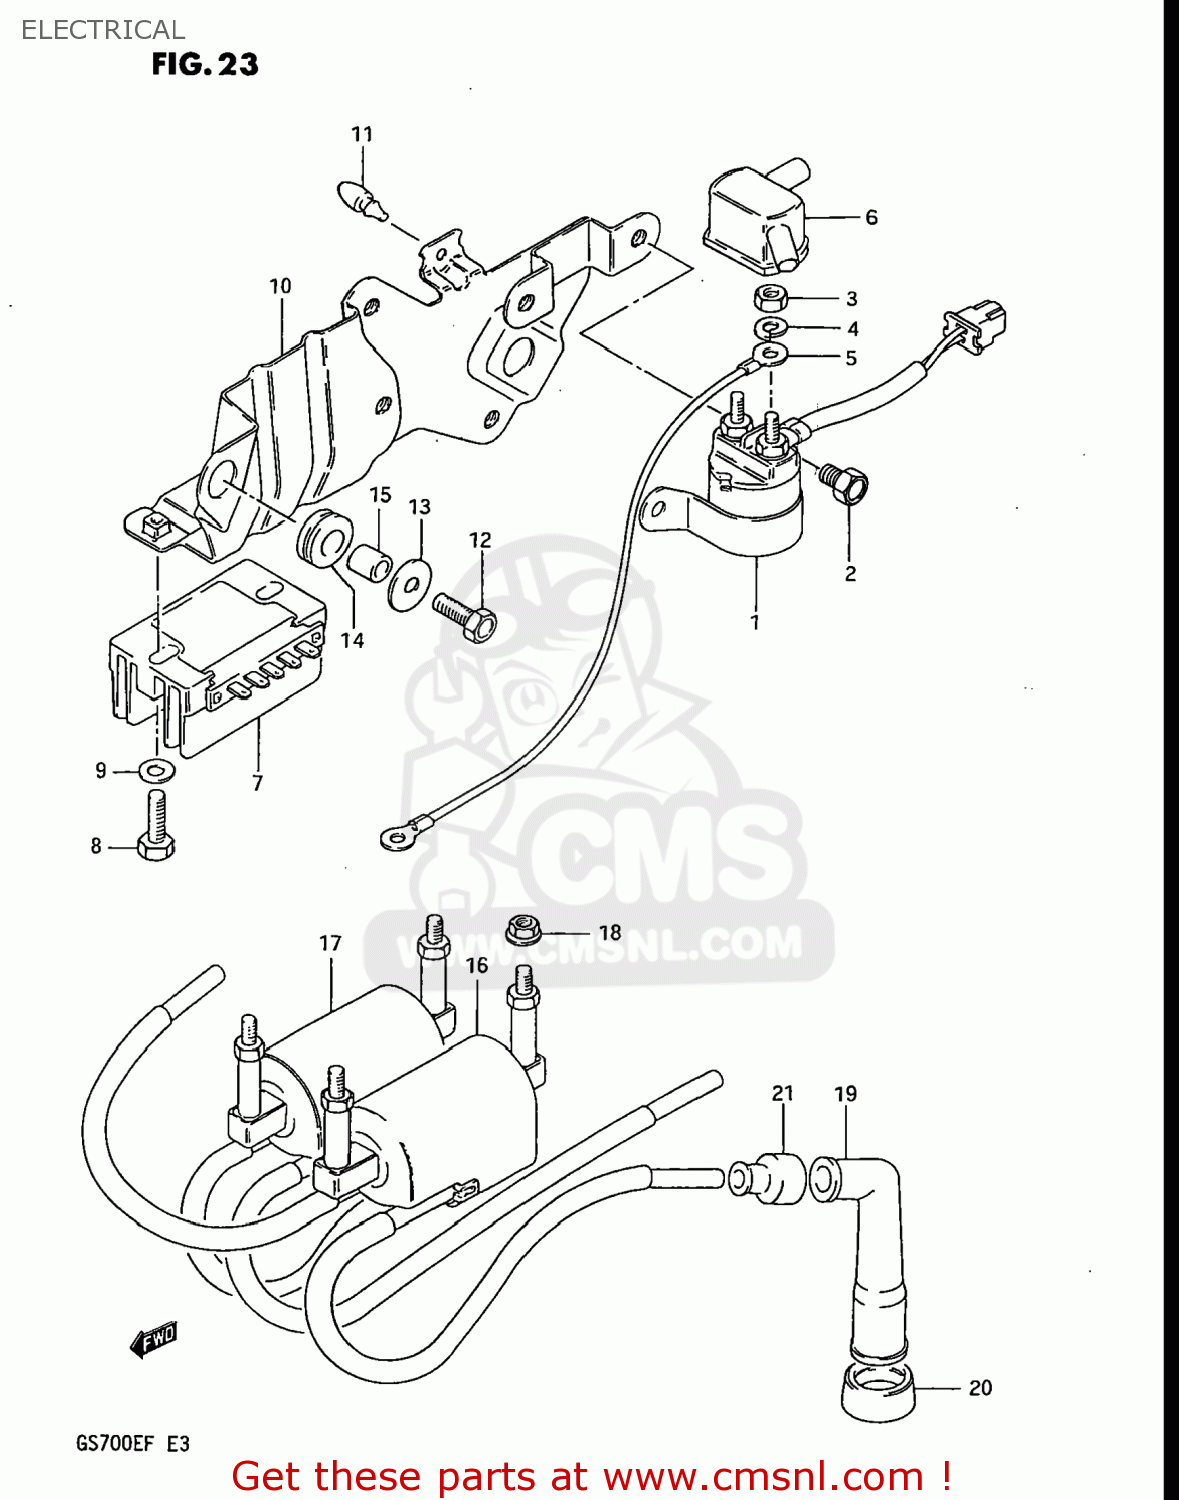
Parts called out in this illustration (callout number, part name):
1	RELAY ASSEMBLY,STARTING MOTOR
2	SCREW(6X10)
3	NUT
4	WASHER,LOCK
5	WIRE,STARTER MOTOR LEAD
6	CAP,STARTER RELAY TERMINAL
7	RECTIFIER ASSEMBLY
8	BOLT(6X20)
9	WASHER
10	PLATE,ELECTRIC PARTS H
11	CUSHION
12	BOLT
13	WASHER (6.5X20X1.2)
14	CUSHION
15	SPACER(6.1X9X7.5)
16	COIL ASSEMBLY,IGNITION
17	COIL ASSEMBLY,IGNITION NO
18	NUT
19	CAP,SPARK PLUG
20	SEAL,SPARK PLUG CAP
21	SEAL,SPARK PLU
